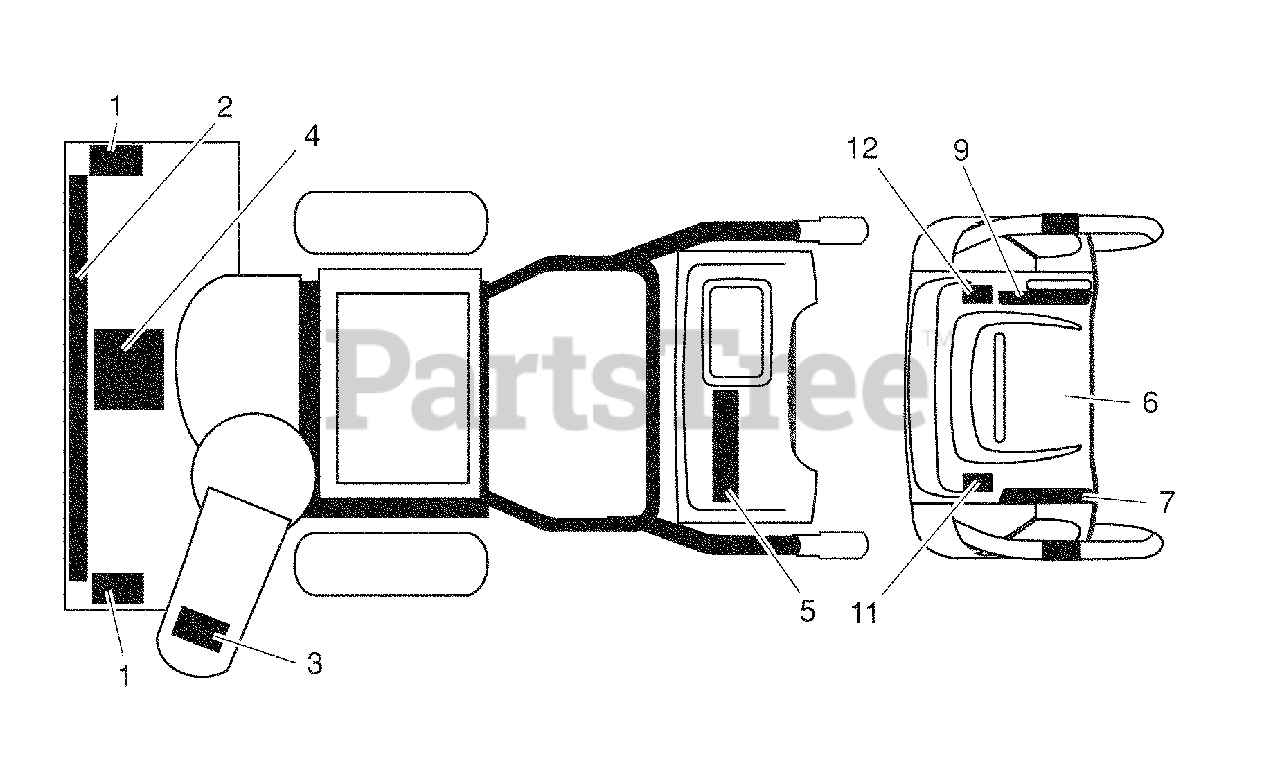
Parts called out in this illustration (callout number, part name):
1	DECAL, DANGER
2	DECAL, HUSQVARNA 1330SB-XLSB
3	DECAL, DANGER, DEFLECTOR
4	DECAL, DANGER
5	DECAL, HUSQVARNA 1330SB-XLSB
6	DECAL, INSTRUCTION
7	DECAL, REMOTE DEFLECTOR
9	DECAL, SPEED CONTROL
11	DECAL, LH TRIGGER
12	DECAL, RH TRIGGER
